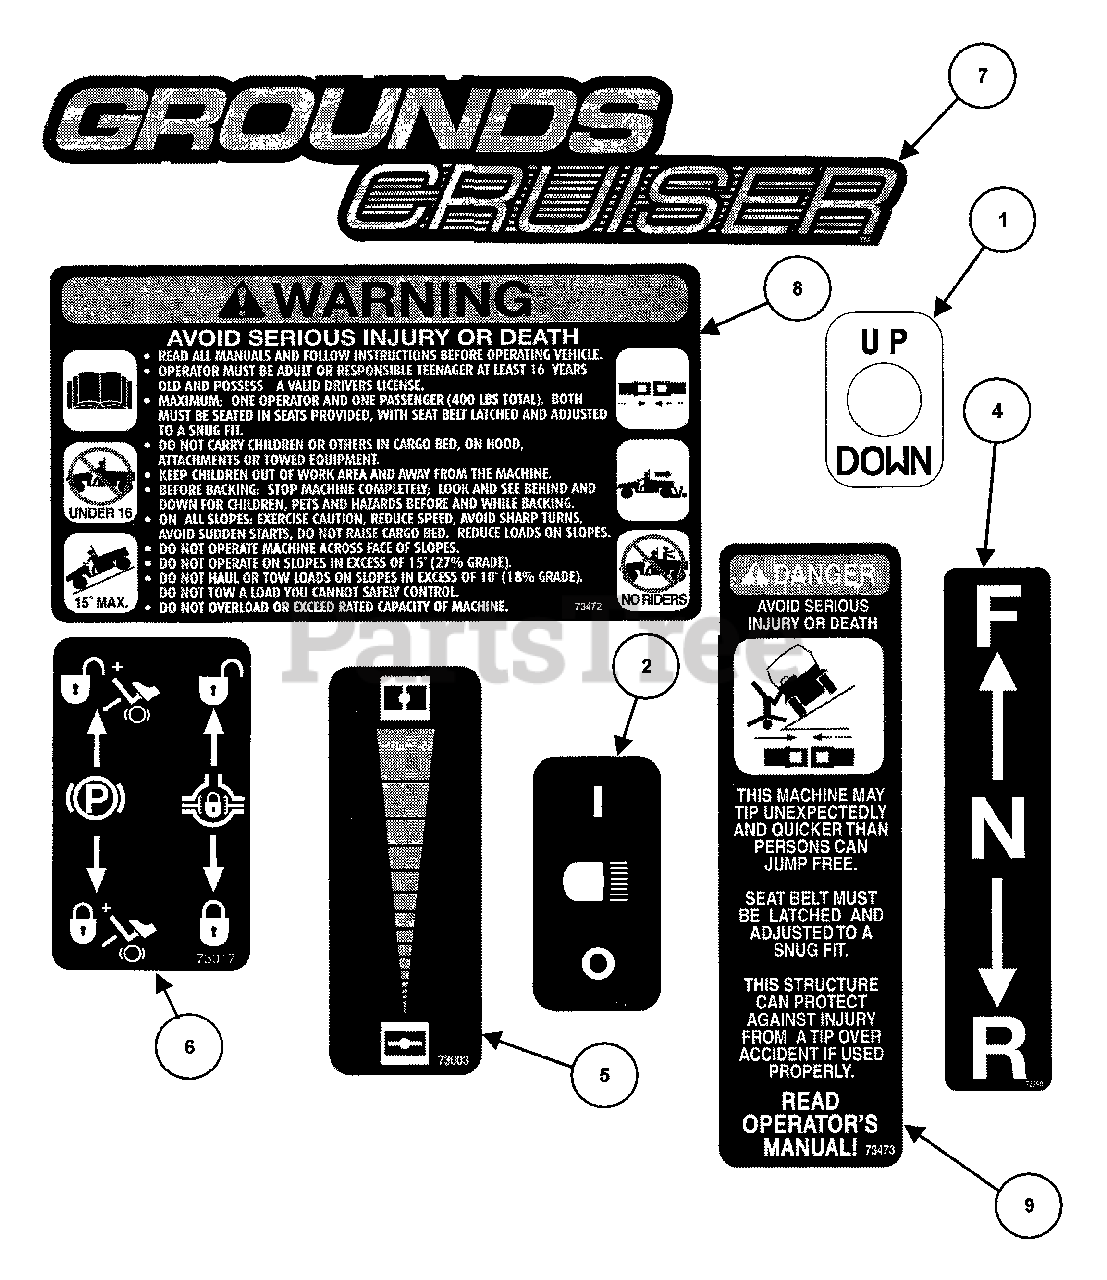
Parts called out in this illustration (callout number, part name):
1	DECAL, BED LIFT
2	DECAL, LIGHT SWITCH
4	DECAL, TRANSMISSION SHIFTER
5	DECAL, CHOKE
6	DECAL, CONSOLE
7	DECAL, GROUNDS CRUISER
8	DECAL, WARNING BILLBOARD
9	DECAL, DANGER ROPS
